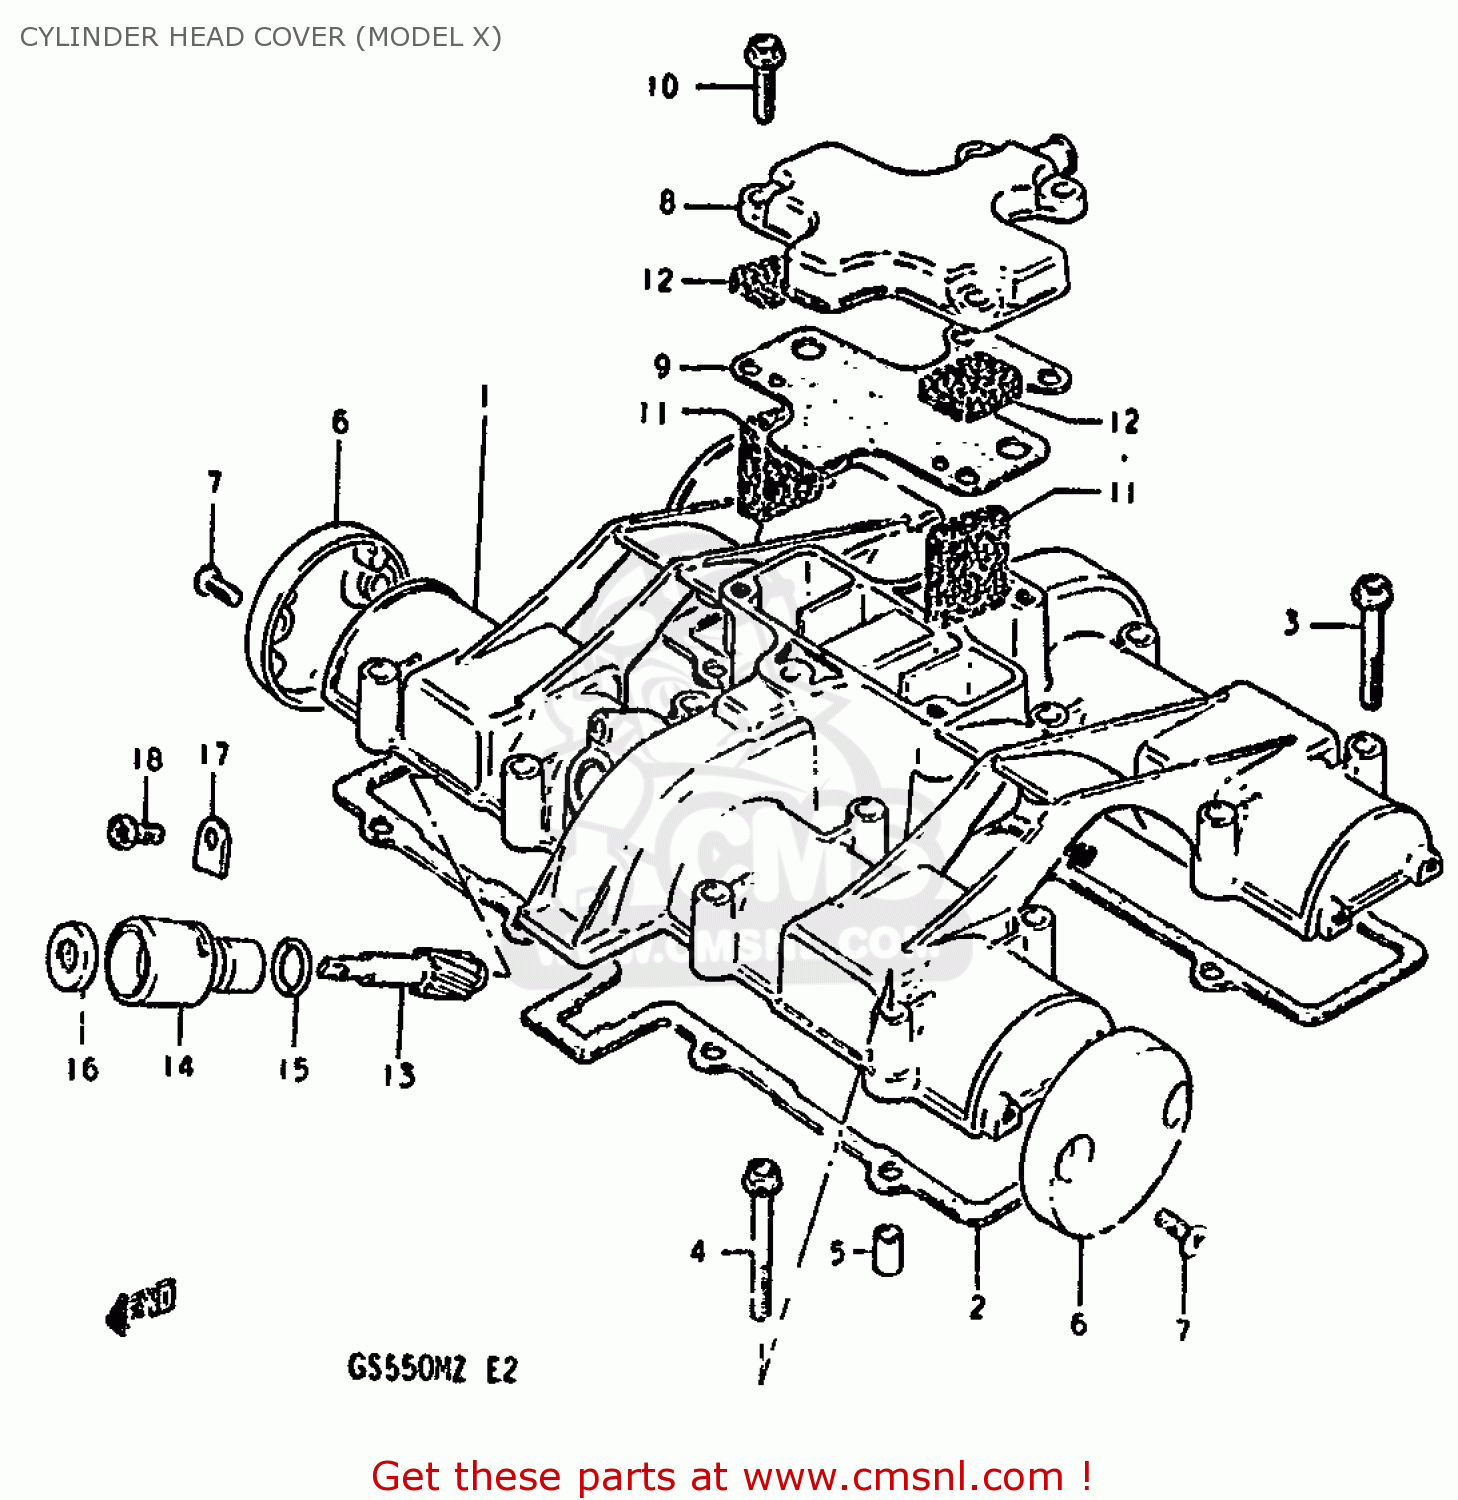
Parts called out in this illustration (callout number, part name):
1	COVER,CYLINDER HEAD
2	GASKET,CYLINDER HEAD COVER (MCA)
3	BOLT
4	BOLT,UNDER
5	PIN(6.2X8X11)
6	CAP,CYLINDER HEAD COVER
7	SCREW(5X12)
8	COVER,BREATHER
9	GASKET (MCA)
10	BOLT,REAR
11	COVER,BREATHER
12	SEPARATOR,OIL BREATHER
13	GEAR,TACHOMETER DRIVEN
14	SLEEVE,TACHOMETER DRIVE
15	SEAL,TACHOMETER DRIVEN
16	SEAL,OIL(5X12X8)
17	PLATE,TACH DRIVE GEAR SLEEVE
18	SCREW(5X12)
